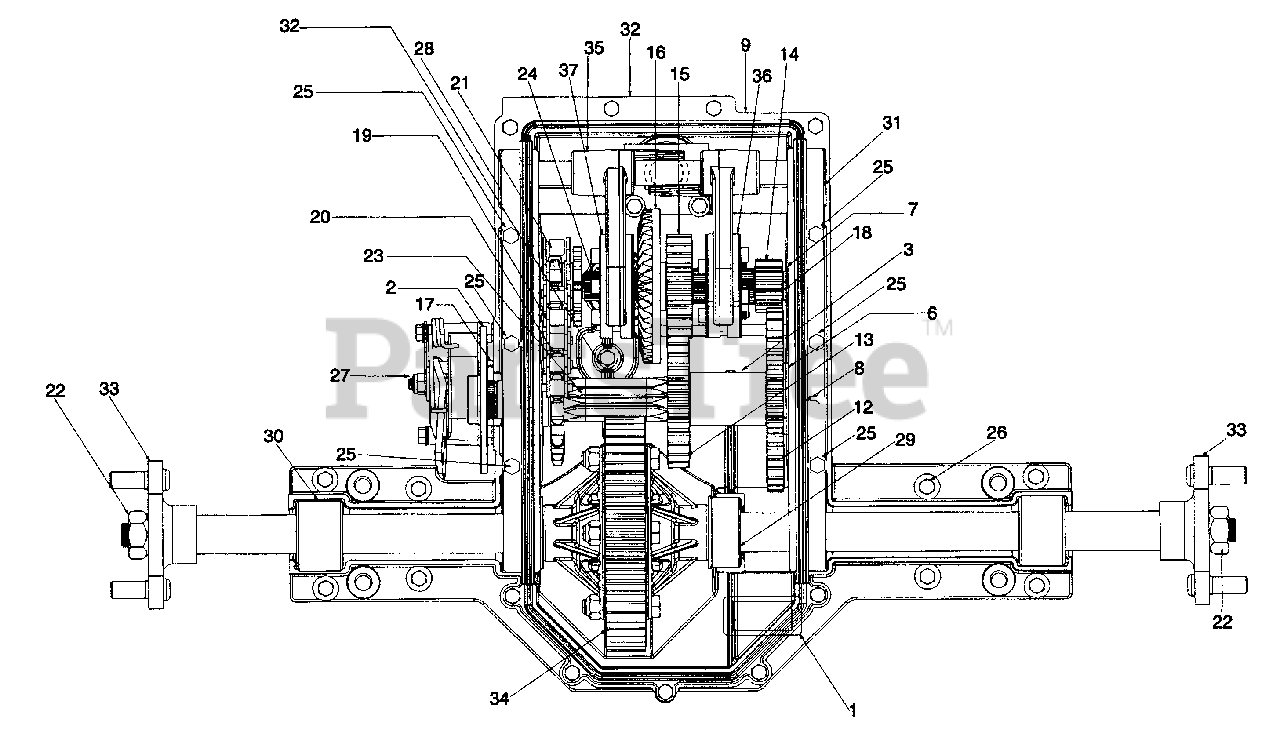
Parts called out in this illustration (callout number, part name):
1	For model I.D. Label
2	Disc Brake
3	Spacer 1.13" I.D. x 1.38" O.D.
6	Stop Washer
7	Fl-Wash. 5/8" I.D. x 1" O.D.
8	Gasket
9	Main Gasket
12	Spur Gear 37T
13	Spur Gear 27T
14	Spur Gear 10T
15	Spur Gear 20T
16	Spur Gear 41T
17	Brake Puck
18	Snap Ring
19	Chain Endless
20	Sprocket 16T
21	Sprocket 9T
22	Lug Nut 5/8-18 Thd.
23	Output Shaft--R.H.
24	Drive Shaft
25	Hex Wash. Hd. TT-Tap Scr. 1/4-20 x 2.62" Lg.
26	Hex Wash. Hd. TT-Tap Scr. 1/4-20 x .75" Lg.
27	Brake Ass'y.--R.H.
28	Bearing Block Ass'y.--R.H.
29	Bearing Block Ass'y.--Inner
30	Bearing Block Ass'y.--Axle
31	Bearing Block Ass'y.--L.H.
32	Housing Ass'y.
33	Hub Ass'y.--Wheel
34	Differential Ass'y.
35	Shift Fork Ass'y.
36	Collar Ass'y.--Hi-Lo
37	Collar Ass'y.--Reverse
